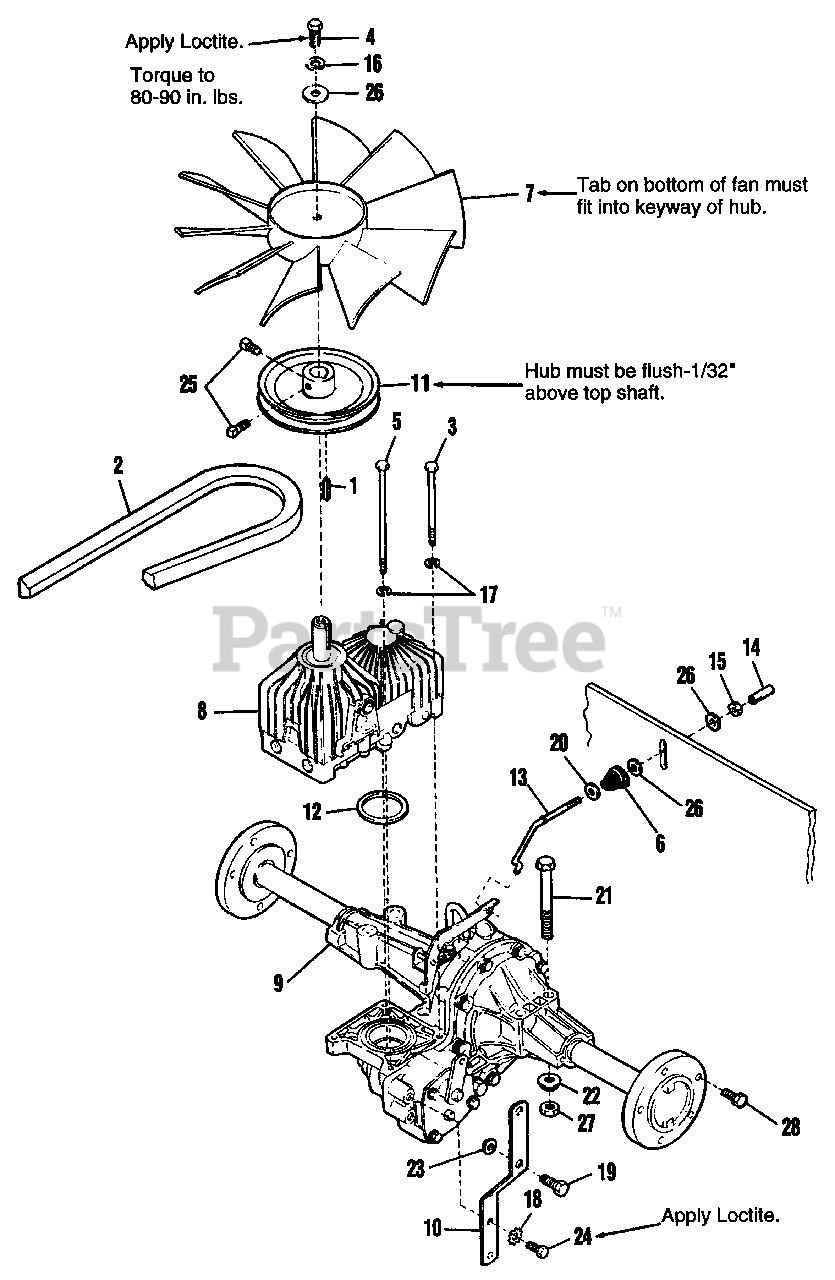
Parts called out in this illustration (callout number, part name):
1	KEY, Parallel
2	BELT, Drive
3	CAPSCREW, Hex Hd., 8 mm-1.25 x 140 mm
4	CAPSCREW, Hex Hd., 6 mm-1.0 x 15 mm
5	CAPSCREW, Hex Hd., 8 mm-1.25 x 80 mm
6	SPRING, Conical
7	FAN, 10 Blade
9	HYDRO TRANSAXLE
10	SUPPORT, Transmission
11	PULLEY
12	GASKET, Rubber
13	ROD, Tow Valve
14	COVER, Vinyl
15	NUT, Hex 1/4-20
16	LOCKWASHER, 1/4
17	LOCKWASHER, 5/16
18	LOCKWASHER, Ext. Tooth, 3/8
19	CAPSCREW, Hex Hd., 3/8-16 x 1
20	WASHER, Flat, 1/4
21	CAPSCREW, Hex Hd., 3/8-16 x 3-1/2
22	NUT, Hex, Flange Lock, 3/8-16
23	NUT, Hex, Flange Lock 3/8-16
24	CAPSCREW, Hex, 10 mm-1.5 x 25 mm
25	SETSCREW, Sq. Hd., 1/4-28
26	WASHER, Flat
27	NUT, Hex, Jam Lock, 3/8-16
28	BOLT, Hub, Rear Wheel
